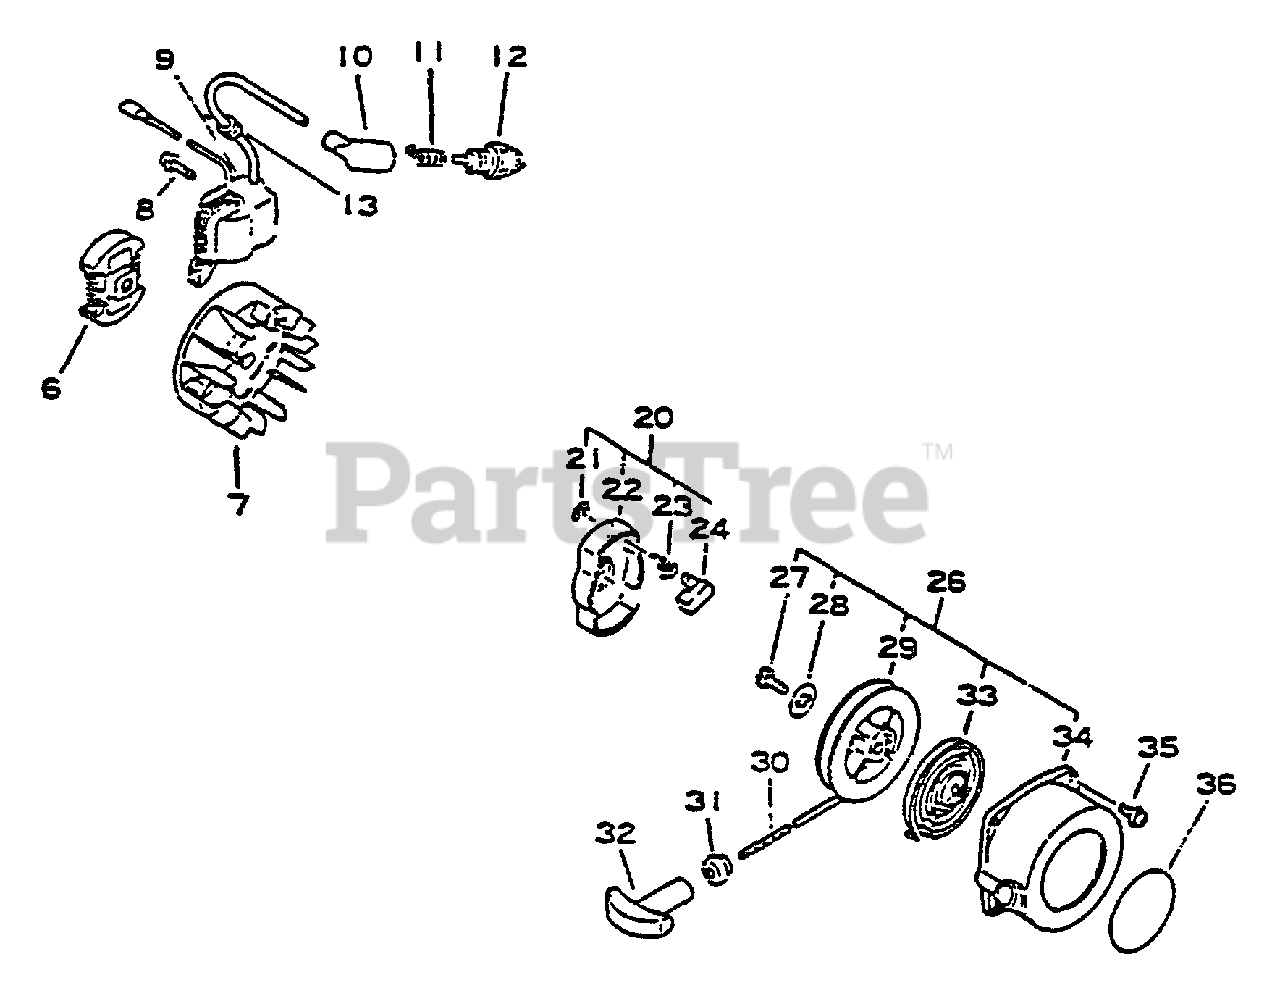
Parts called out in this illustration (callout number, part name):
6	CLUTCH ASSY
7	FLYWHEEL
8	SCREW - 4X22
9	COIL, IGNITION
10	CAP, SPARK PLUG
11	TERMINAL, SPARK PLUG CAP
12	SPARK PLUG -- BPM-7A
12	SPARK PLUG -- BPMR-7A
13	GROMMET
20	STARTER PAWL ASSY
21	RING, RETAINING - 4
22	CATCHER, PAWL
23	SPRING, RETURN
24	PAWL, STARTER
26	STARTER ASSY
28	WASHER
29	REEL, ROPE
30	ROPE, STARTER - 3X890
31	GUIDE, ROPE
32	GRIP, STARTER
33	SPRING, REWIND
34	CASE, STARTER
35	SCREW - 4X16
36	LABEL - ECHO
